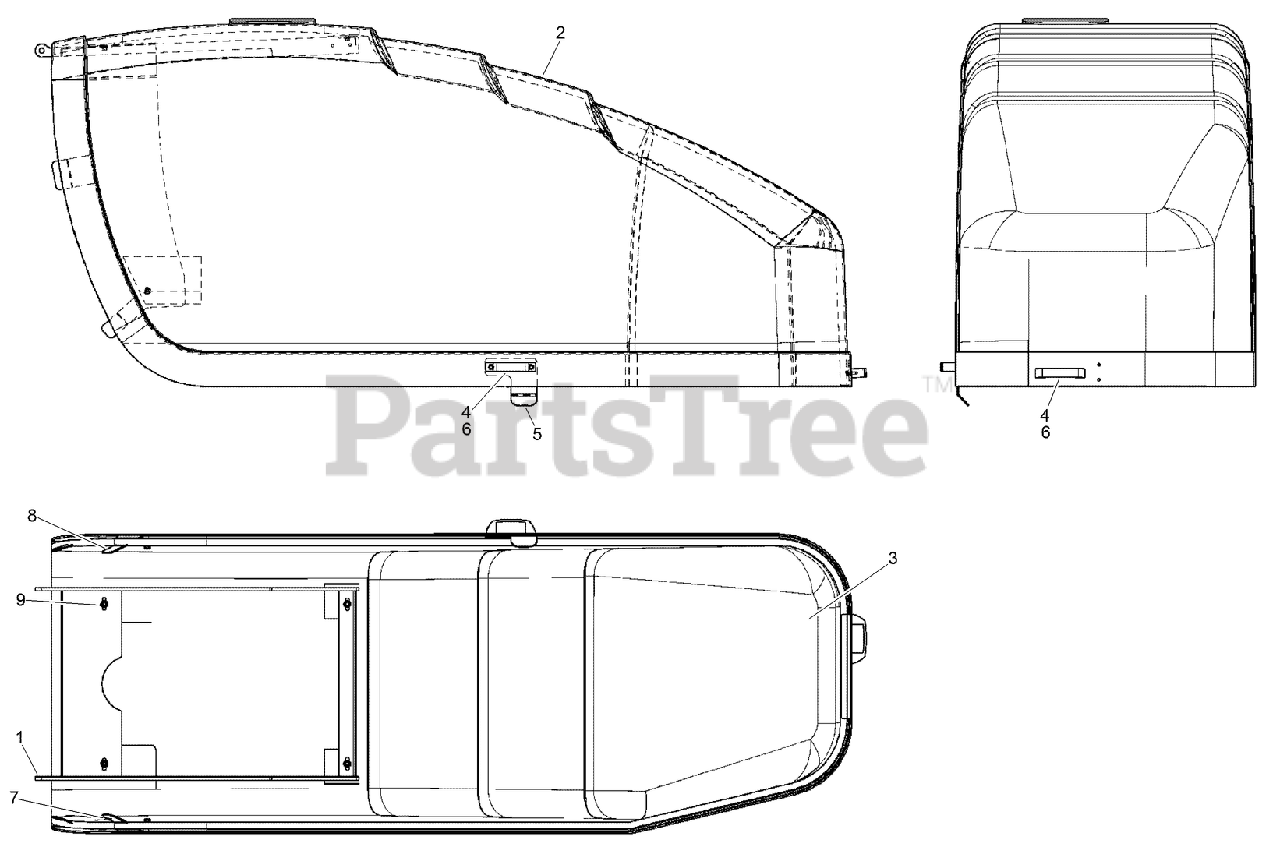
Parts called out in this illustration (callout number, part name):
1	HINGE-HOOD, FRONT
2	HOOD-FRONT
3	LINING - Sound and Heat Resistant
4	HANDLE-GRAB
5	GUIDE-HOOD, FRONT
6	SCREW, METRIC FLANGE w/BODY - M8 x 20
7	PLATE-CATCH, HOOD
8	PLATE-CATCH, HOOD
9	NUT-Serr Flg 3/8-16 UNC GR5 ZND
